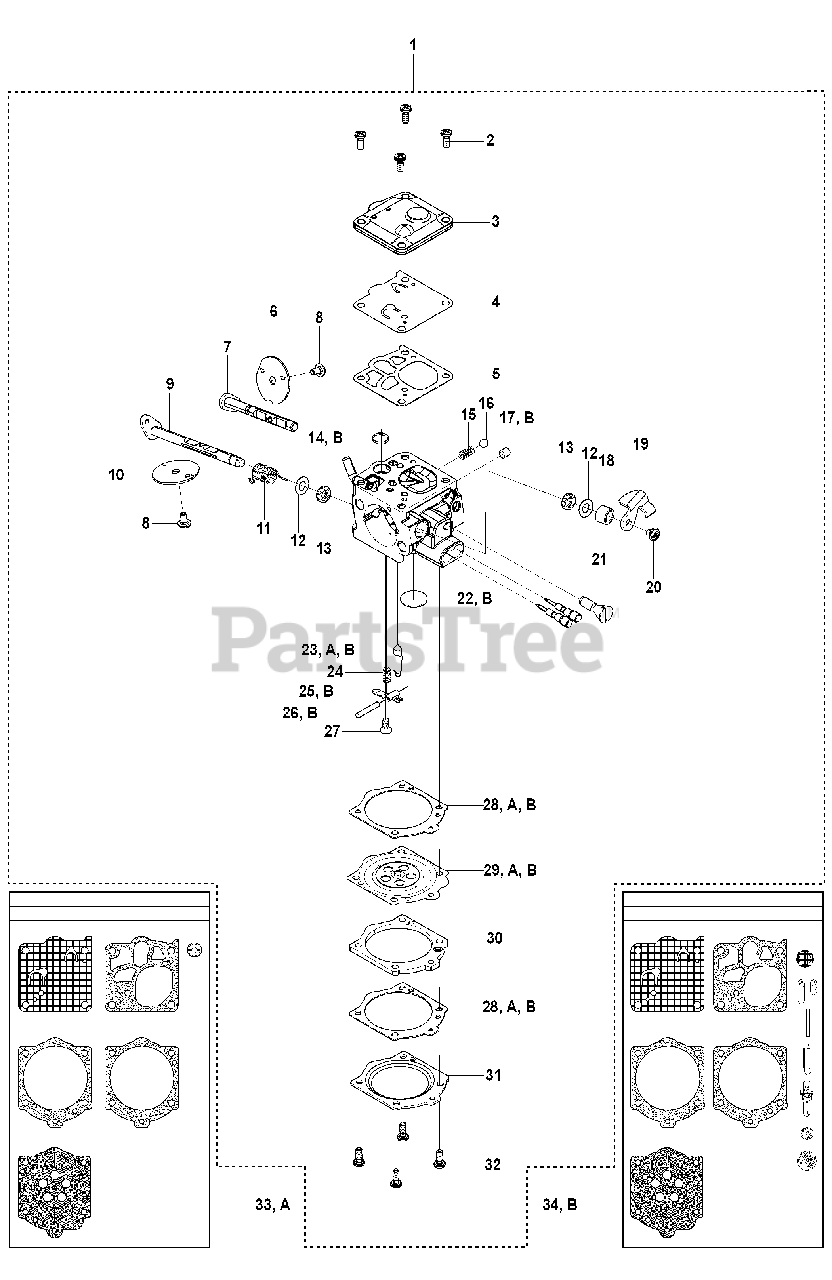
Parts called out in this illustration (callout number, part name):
1	CARBURETTOR
2	SCREW-PUMP COVER
3	PUMP COVER
4	DIAPHRAGM PUMP
5	GASKET-PUMP
13	SEAL-THROTTLE SHAFT
14	SCREEN-INLET
15	SPRING-CHOKE FRICT.
16	BALL-CHOKE FRICTION
22	PLUG-WELCH
23	VALVE -INLET NEEDLE
24	SPRING-METER.LEVER
25	LEVER-METERING
26	PIN-METERING LEVER
27	SCREW-LEVER PIN
28	GASKET
29	DIAPHRAGM ASSY
33	GASKET KIT
34	REPAIR KIT
